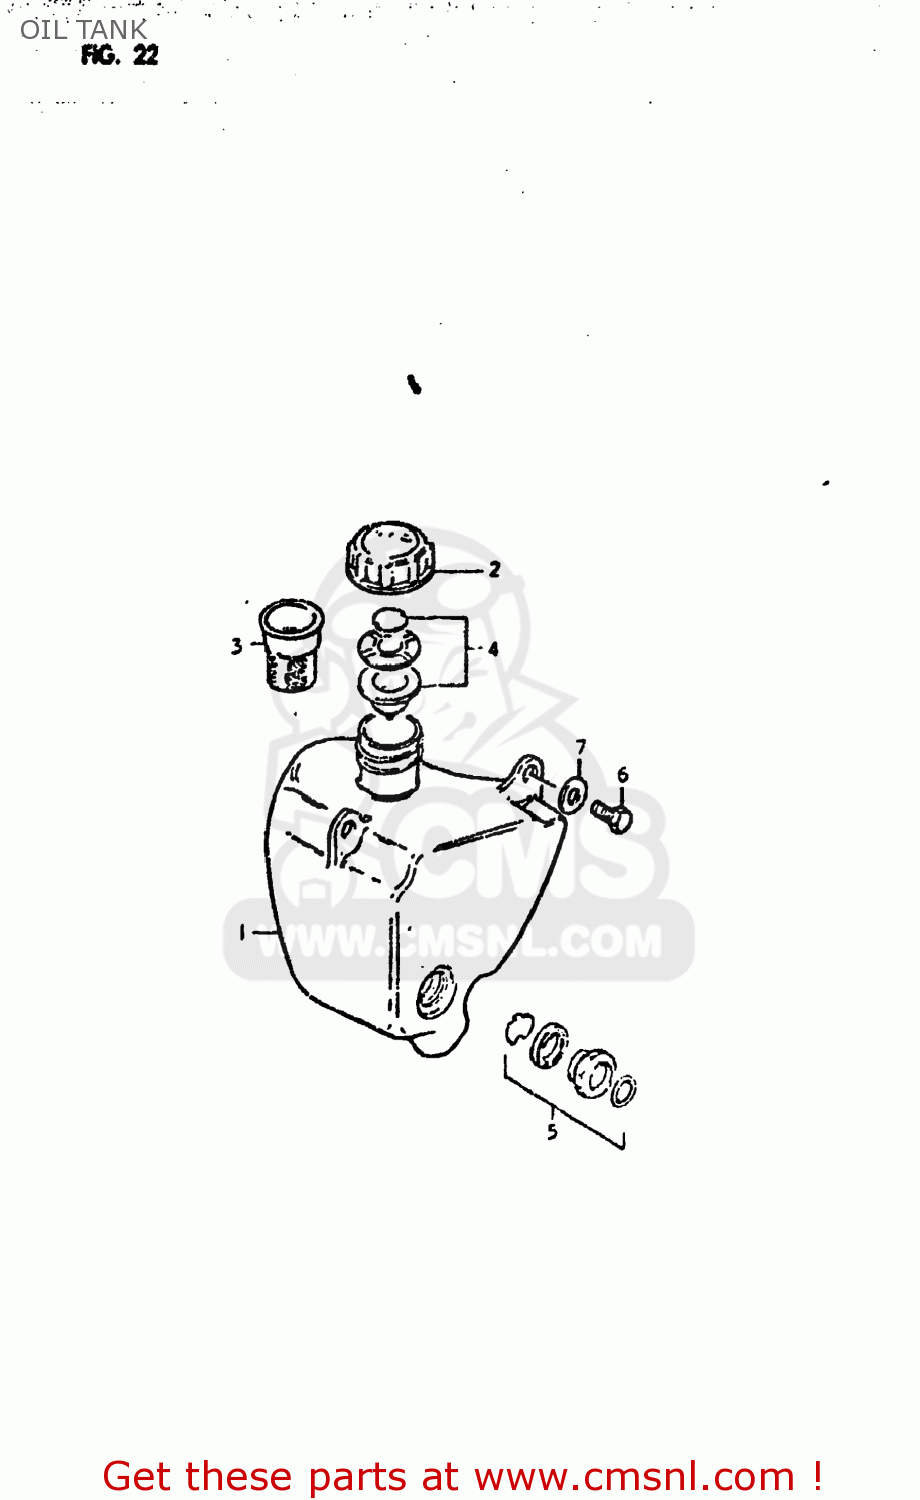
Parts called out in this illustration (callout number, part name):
1	TANK,OIL
2	CAP,OIL TANK
3	FILTER,OIL TANK INLET
4	GASKET SET (NAS)
5	LENS SET,OIL LEVEL
6	BOLT
7	WASHER
